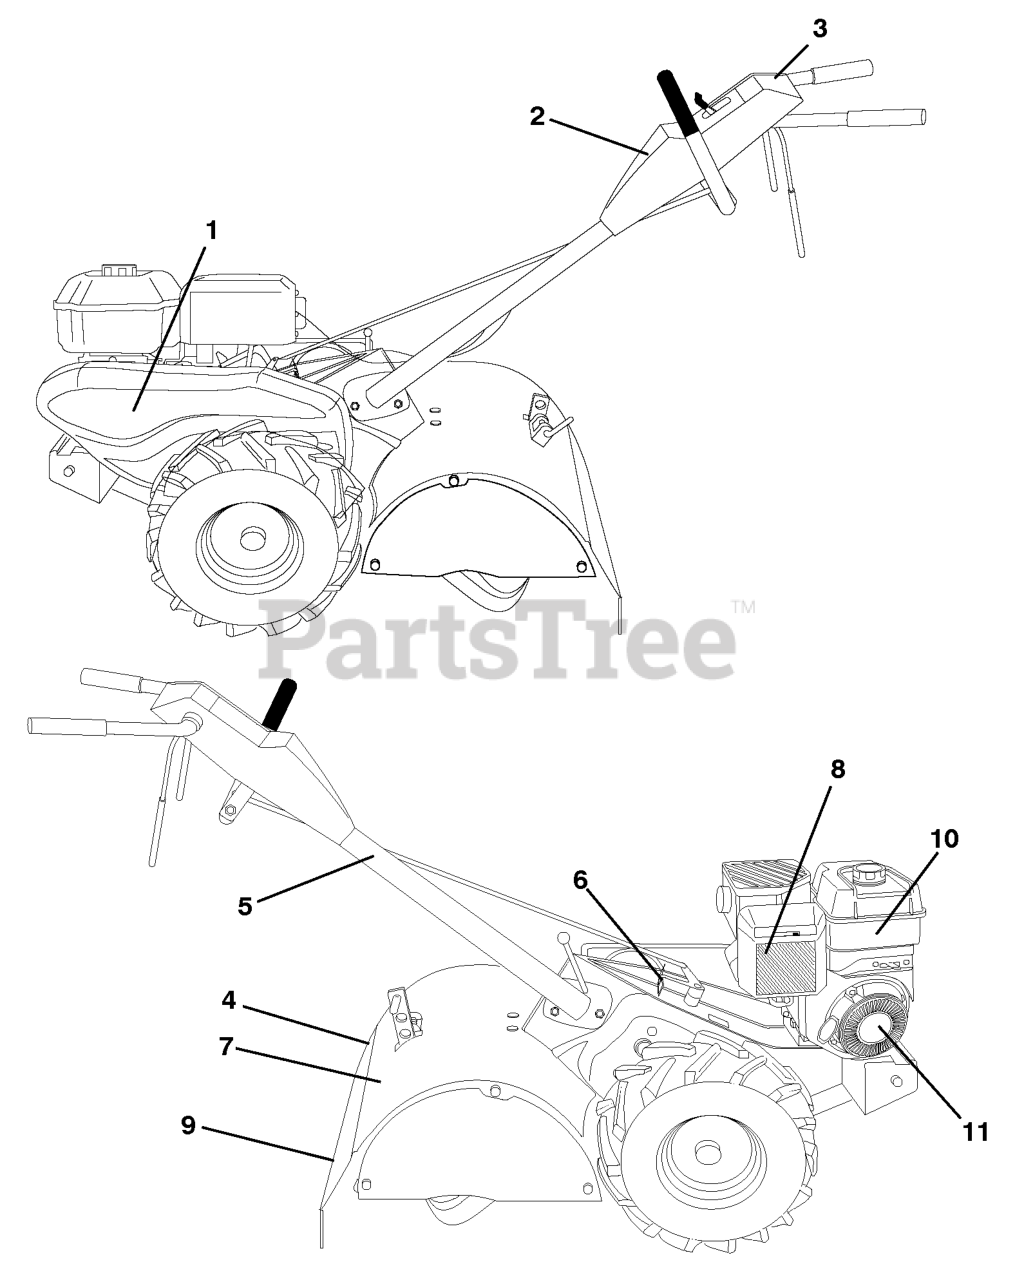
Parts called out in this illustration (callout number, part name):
1	RP.DECAL.BADGE.170MM.TEXTLOGO
2	DECAL, HUSQVARNA,CONTROL PANEL
3	DECAL, CONTROL TINE
4	DECAL.SHIELD
5	DECAL TI (2 2)
6	DECAL.SHIFT.INDICATOR.TILLER
7	DECAL.WARNING.SHLD.ENG/FR
8	DECAL.BS.850.A/C.REF.277442
9	DECAL TI
10	DECAL.BS.850.TANK.REF.276929
11	DECAL, REWIND STARTER, B&S
